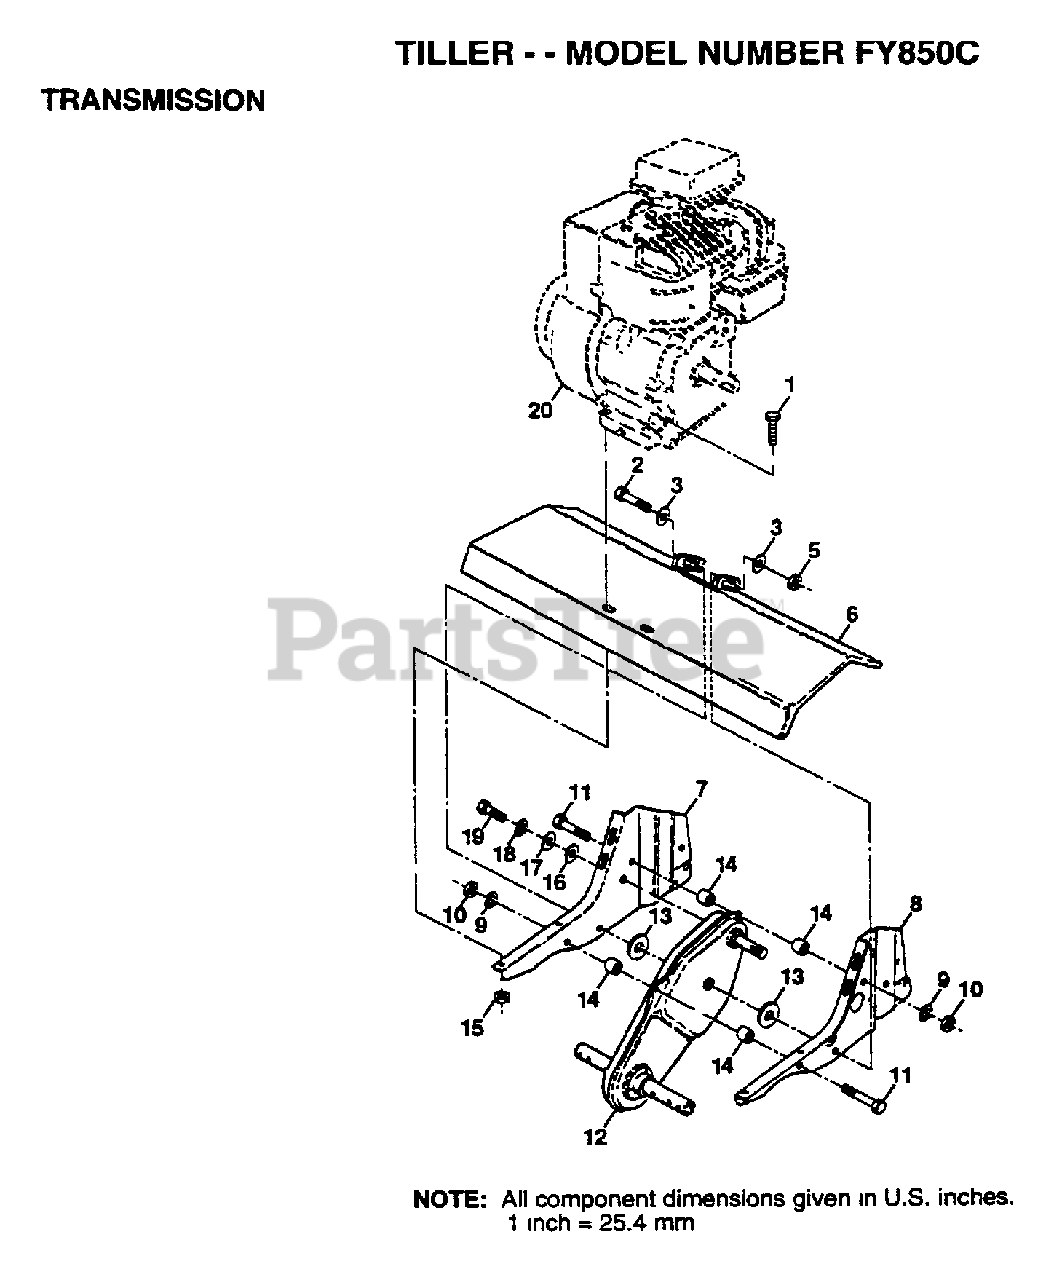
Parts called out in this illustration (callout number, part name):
1	BOLT.HEX.5/16-1.5
2	BOLT HEX 3/8-16
3	WASHER
5	NUT
6	"SHIELD, TINE"
9	LOCKWASHER
10	NUT.HEX.5/16-18
14	SPLIT SPACER RT
16	WASHER
17	WASHER
18	LOCKWASHER
19	BOLT
